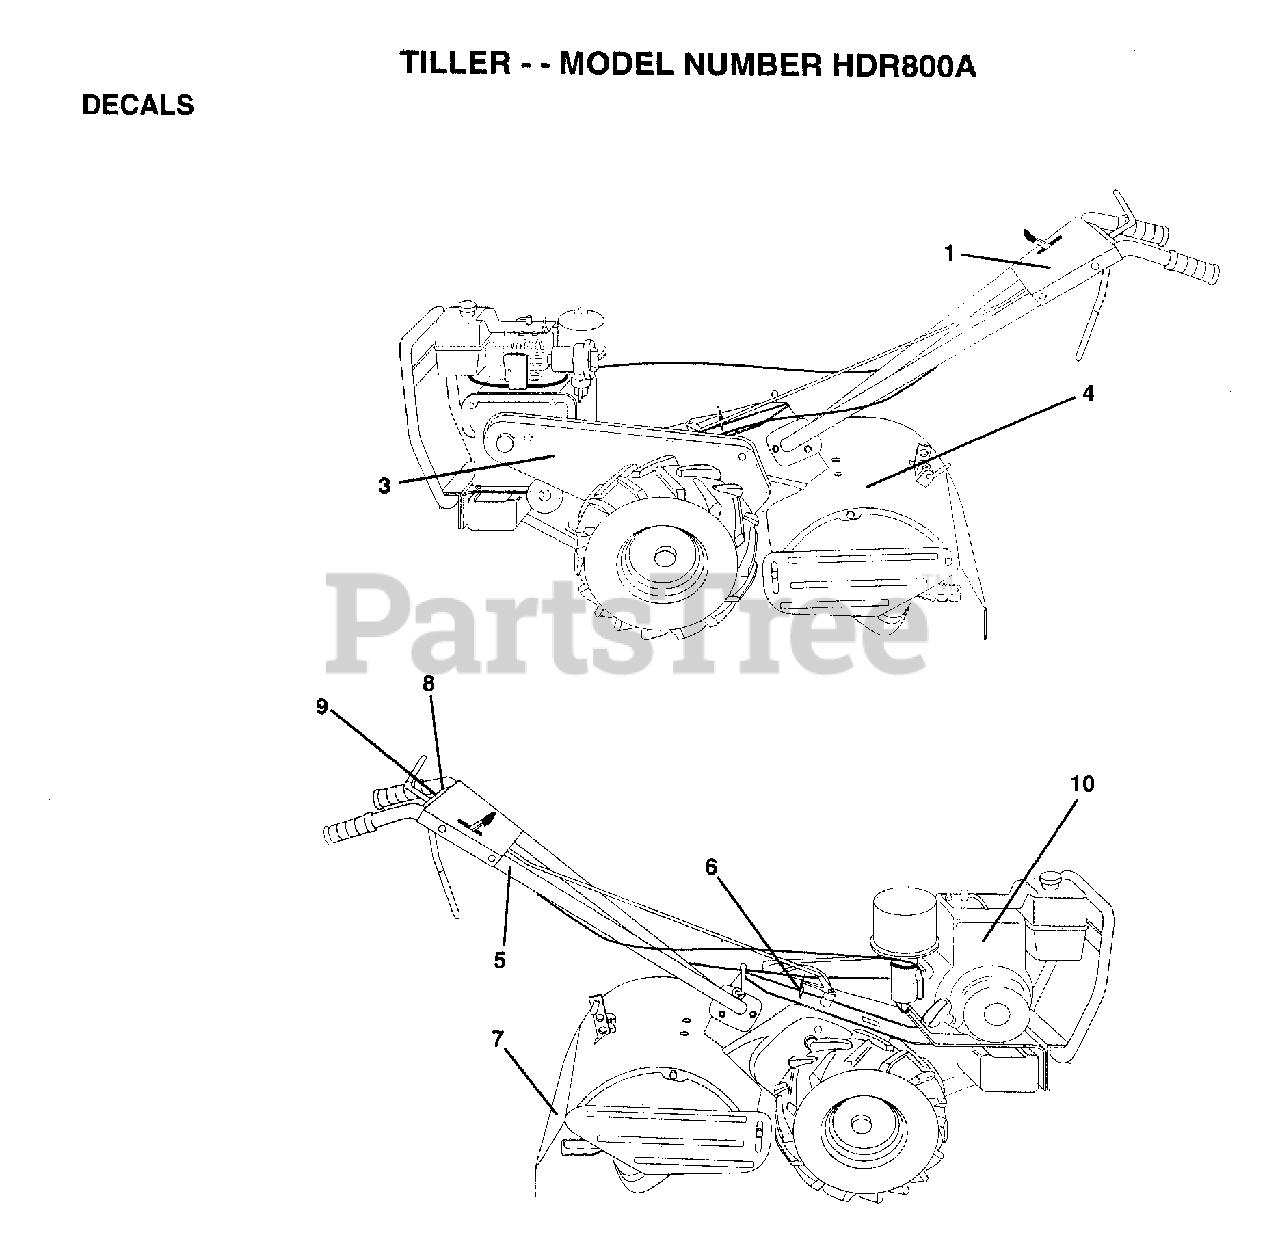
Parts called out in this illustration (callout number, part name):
4	DECAL.SHIELD.TINE
5	DECAL.HAND.PLACE
6	DECAL CRT
7	DECAL.WARN.ROT.TI
8	DECAL.CONTROL
9	DECAL.CAUTION.E/S
10	DECAL, BRIGGS & STRATTON
